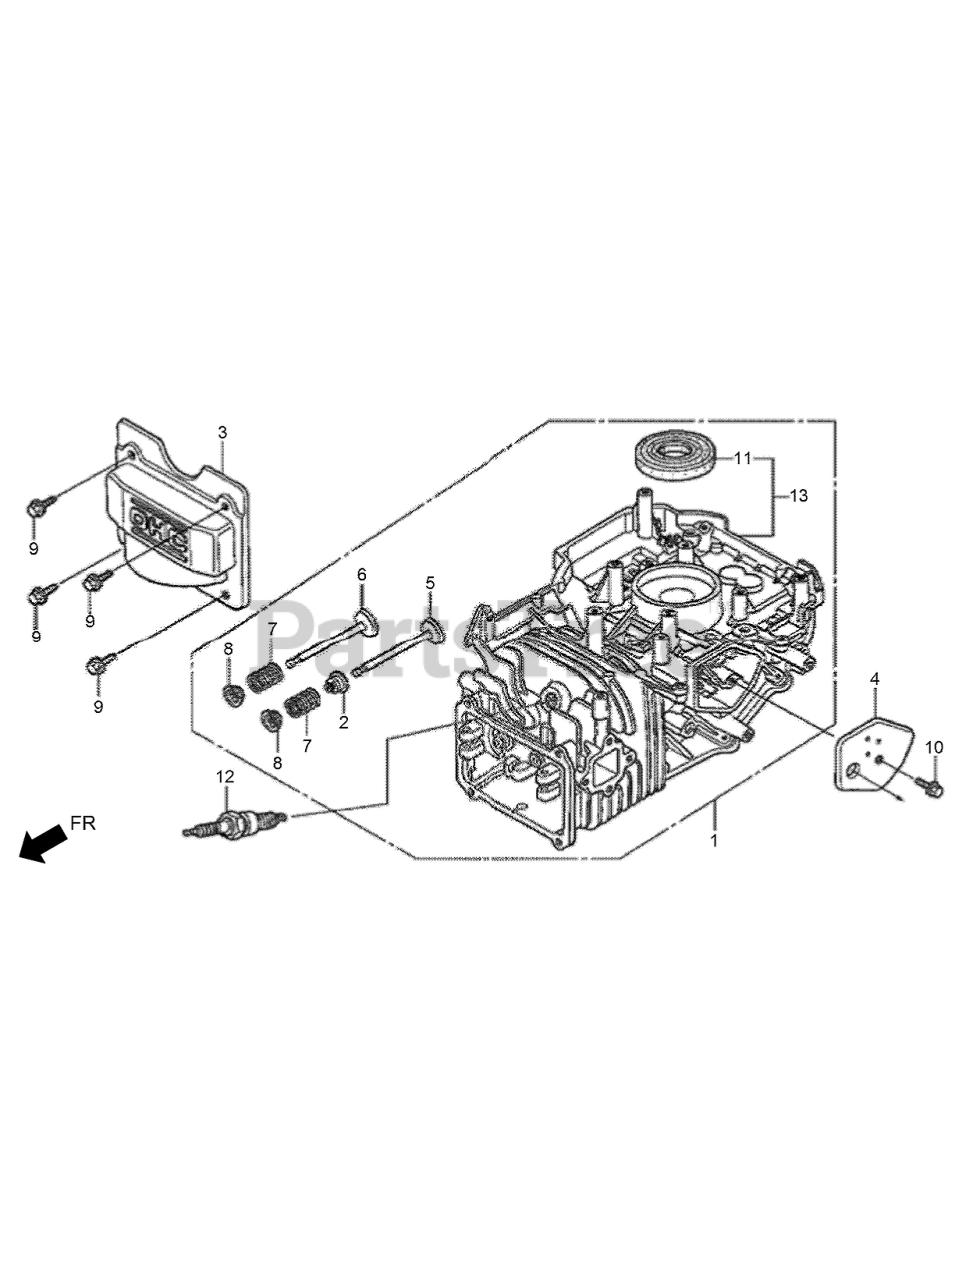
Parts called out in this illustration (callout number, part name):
1	BARREL ASM-CYLINDER (to S/N 4079546)
2	SEAL-VALVE STEM
3	COVER-HEAD
4	BREATHER COVER ASM
5	VALVE-INTAKE
6	VALVE-EXHAUST
7	SPRING-VALVE
8	RETAINER-INTAKE VALVE SPRING
9	BOLT-FLANGE-6X12
10	BOLT-FLANGE-6X14
11	OIL SEAL-25.4X62X6
12	SPARKPLUG
13	BARREL ASM-CYLINDER (from S/N 4079547 to 4408691)
13	BARREL ASM-CYLINDER (from S/N 4408692)
